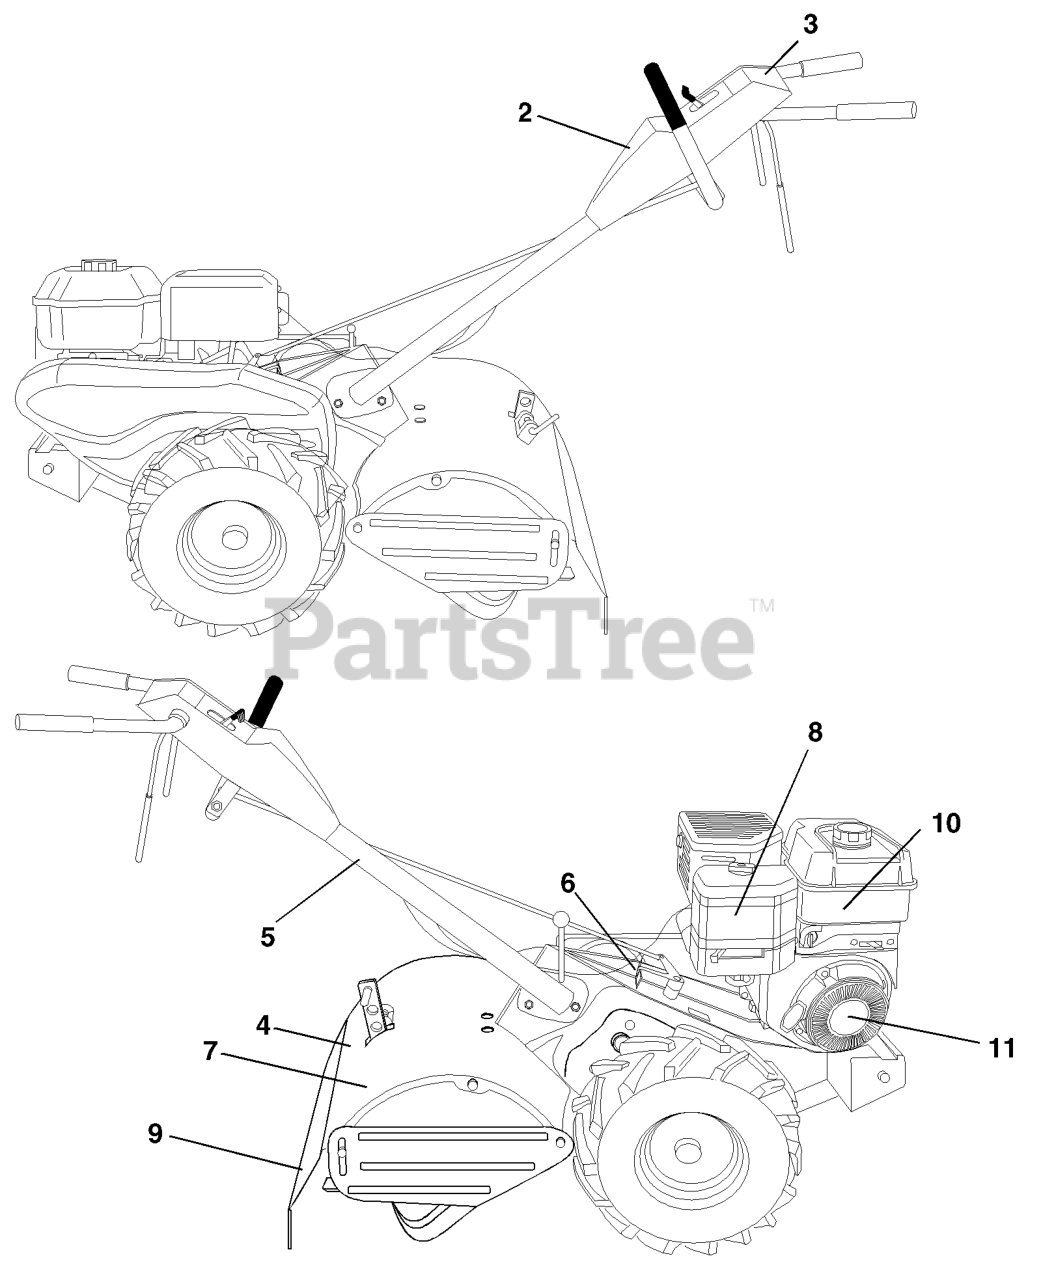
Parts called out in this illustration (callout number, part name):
2	DECAL, CONTROL PNL
3	DECAL.CONTROL.TINE.SPLIT LOOP
4	DECAL, TINESHEILD
5	DECAL TI (2 2)
6	DECAL.SHIFT.INDICATOR.TILLER
7	DECAL -CAUTION
8	DECAL, ENG. B&S 6.5HP
9	DECAL TI
10	DECAL, ENGINE INTEK REF
11	DECAL.REWIND
